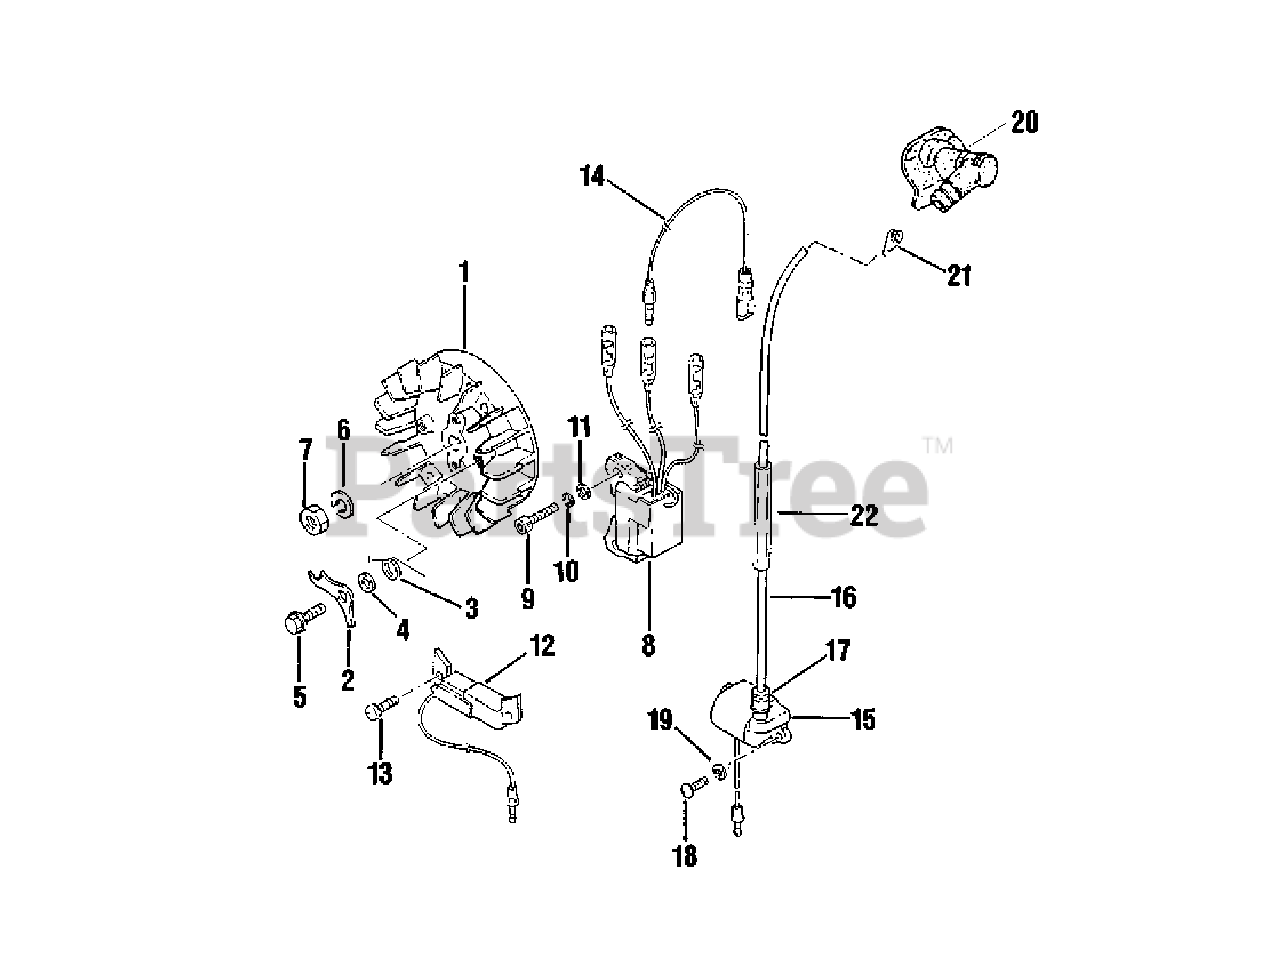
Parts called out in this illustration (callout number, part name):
1	ROTOR
2	PAWL, STARTER
3	SPRING, RETURN
4	WASHER - 6
5	BOLT
6	LOCKWASHER - 8
7	NUT
8	EXCITER, COIL
9	SCREW - 5X20
10	LOCKWASHER - 5
11	WASHER - 5
12	PULSER COIL
13	SCREW - 4X12
15	COIL, IGNITION
17	CAP
18	SCREW - 4X12
19	WASHER
20	CAP, SPARK PLUG
21	TERMINAL, SPARK PLUG CAP
22	PROTECTOR
